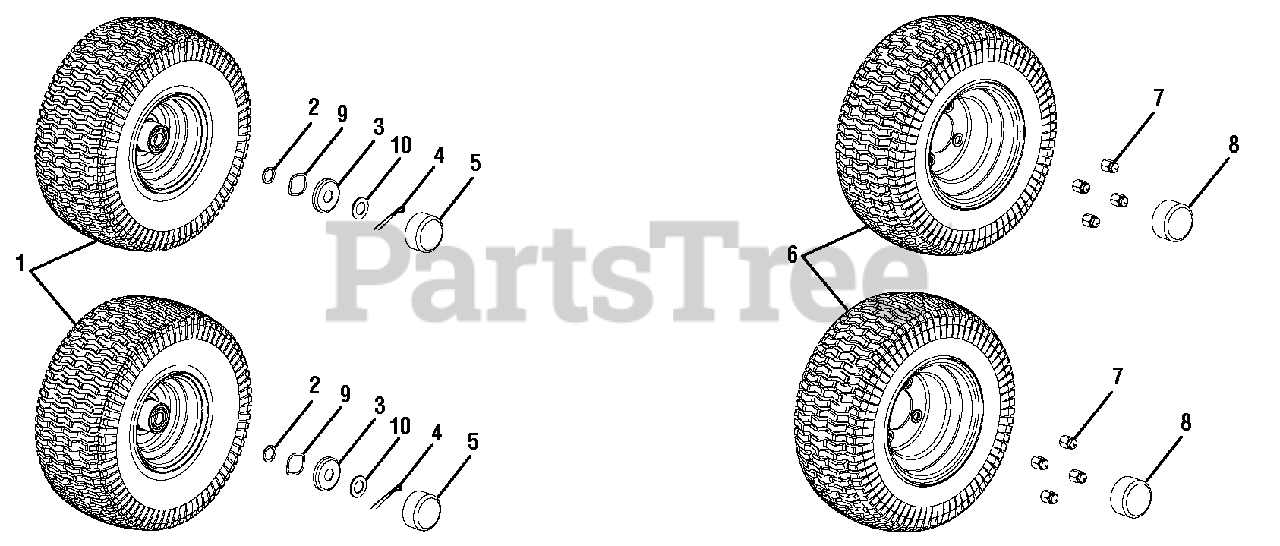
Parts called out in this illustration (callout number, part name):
1	Front Wheel Assembly
2	Washer (OD28 x ID20.5 x 2t)
3	Front Wheel Bearing Cover
4	Cotter Pin (4 x 40 mm)
5	Dust Cover, Front Wheel
6	Rear Wheel Assembly
7	Acorn Nut (M14)
8	Wheel Hub Cover
9	Wavy Washer
10	Washer (OD37 x ID21 x 0.3t)
